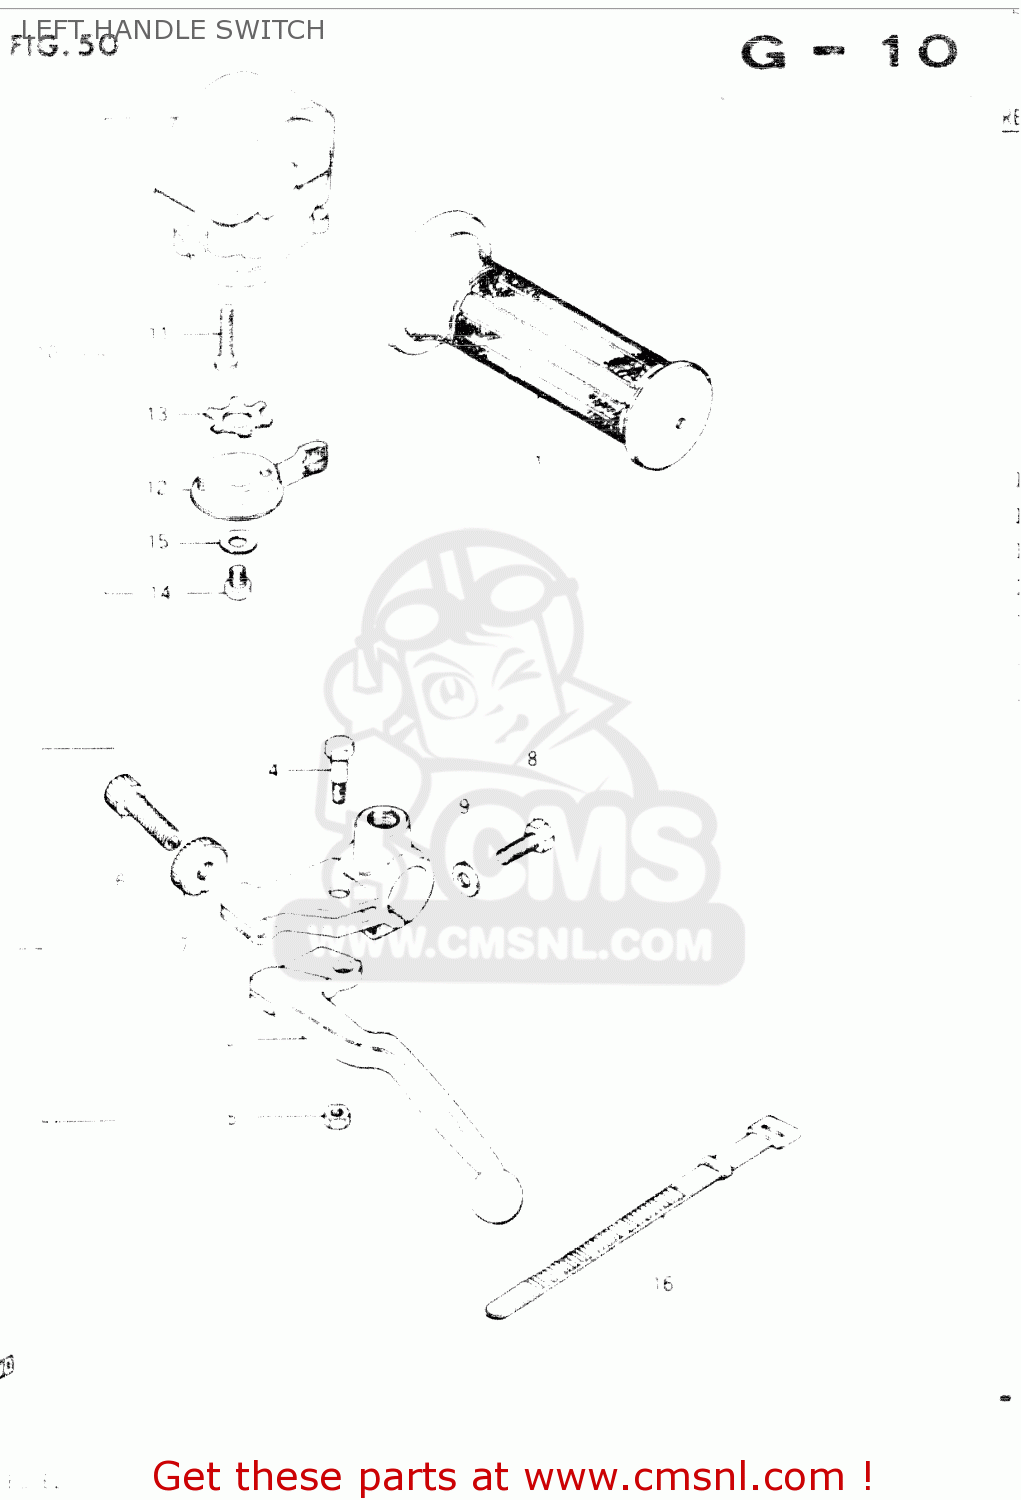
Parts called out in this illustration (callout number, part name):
1	GRIP,L
2	LEVER ASSEMBLY,CLUTCH
3	LEVER,CLUTCH
4	BOLT,LEVER PIVOT
5	NUT
6	ADJUSTER,CABLE
7	NUT,CABLE ADJUSTER LOCK
8	BOLT
9	WASHER
10	SWITCH ASSY,HA
11	SCREW
12	LEVER,STARTER
13	WASHER
14	WASHER
15	WASHER 6MM
16	CLAMP(L:120)
